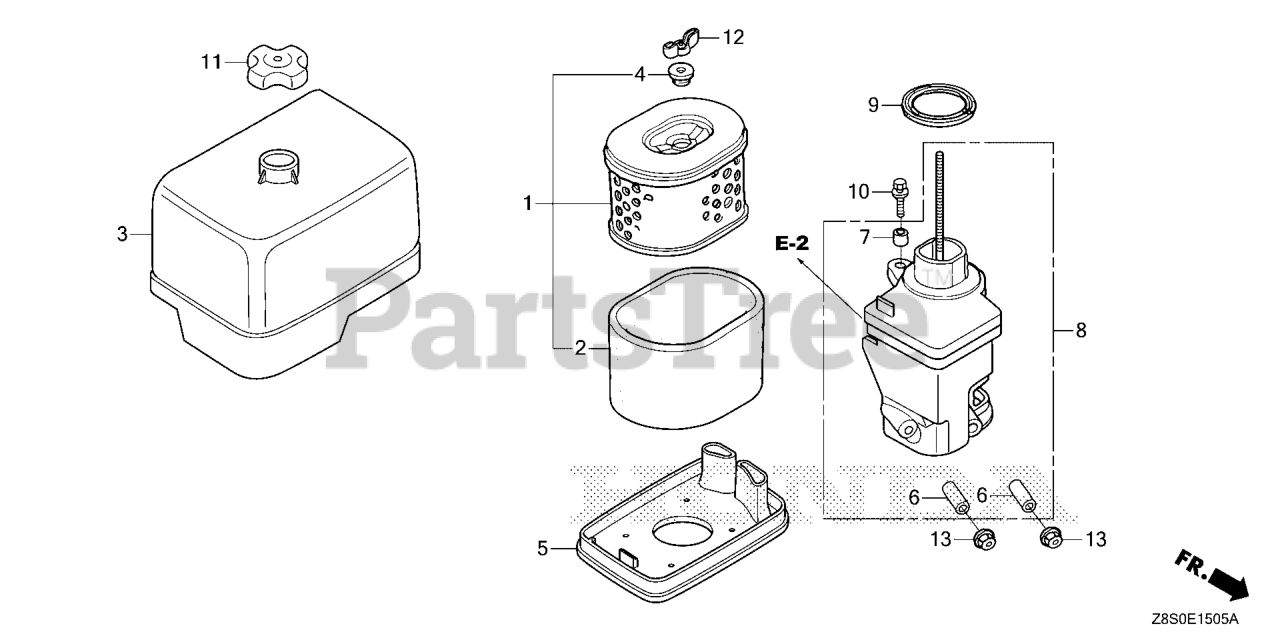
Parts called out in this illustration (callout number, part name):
1	ELEMENT, AIR CLEANER (DUAL)
2	FILTER (OUTER)
3	COVER, AIR CLEANER HOUSING
4	GROMMET, AIR CLEANER
5	NOSE, MUFFLER
6	COLLAR, AIR CLEANER
7	COLLAR B, AIR CLEANER
8	ELBOW, AIR CLEANER
9	GASKET, AIR CLEANER HOUSING
10	BOLT-WASHER (6X22)
11	NUT, AIR CLEANER COVER
12	WINGNUT, TOOL BOX SETTING
13	NUT, FLANGE (6MM)
